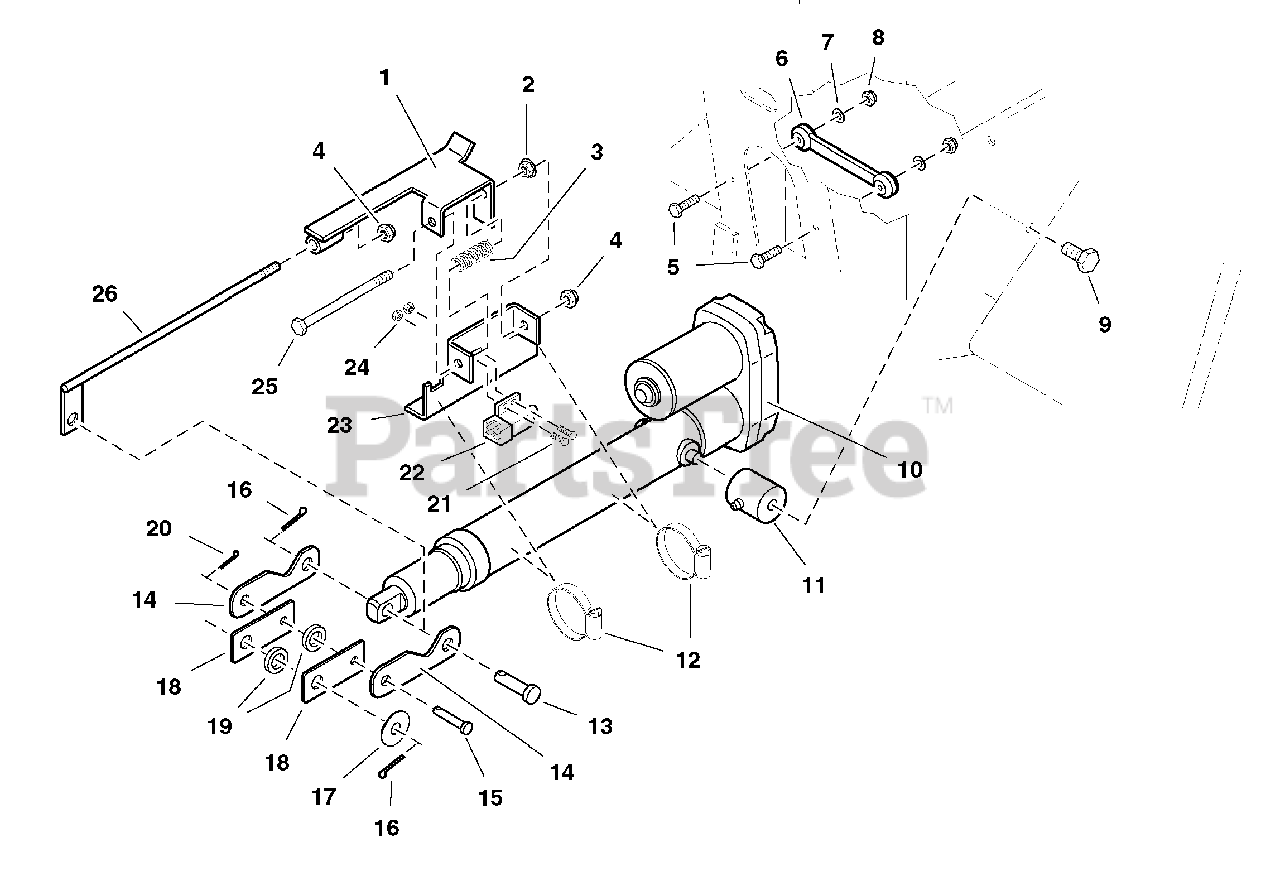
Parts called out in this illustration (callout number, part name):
1	SWITCH STRIKE BRACKET
2	NUT, Hex, Serrated Flange, 5/16-18
3	SPRING, Compression
4	NUT, Hex, Nylon Lock, 5/16-18
5	BOLT, 1/4-20 X 1", GD
6	RUBBER STRAP
7	WASHER, 1/4 SAE (5025154)
8	NUT, Hex, Nylon Lock, 1/4-20
9	CAPSCREW, Hex Hd, 3/8-16 x 1
10	ELECTRIC ACTUATOR
11	ACTUATOR MOUNT
12	HOSE CLAMP, #40
13	PIN, Clevis
14	ACTUATOR LINK, Lower
15	PIN, Clevis
17	WASHER, 5/8
18	ACTUATOR LINK, Upper
20	PIN,Cotter
21	SCREW, Phillips Hd, #10-24 x 1
22	SWITCH, Plunger, NO/NO
23	ACTUATOR SWITCH MOUNT
24	NUT, Hex, #10-24
25	CAPSCREW, Hex Hd, 5/16-18 x 5
